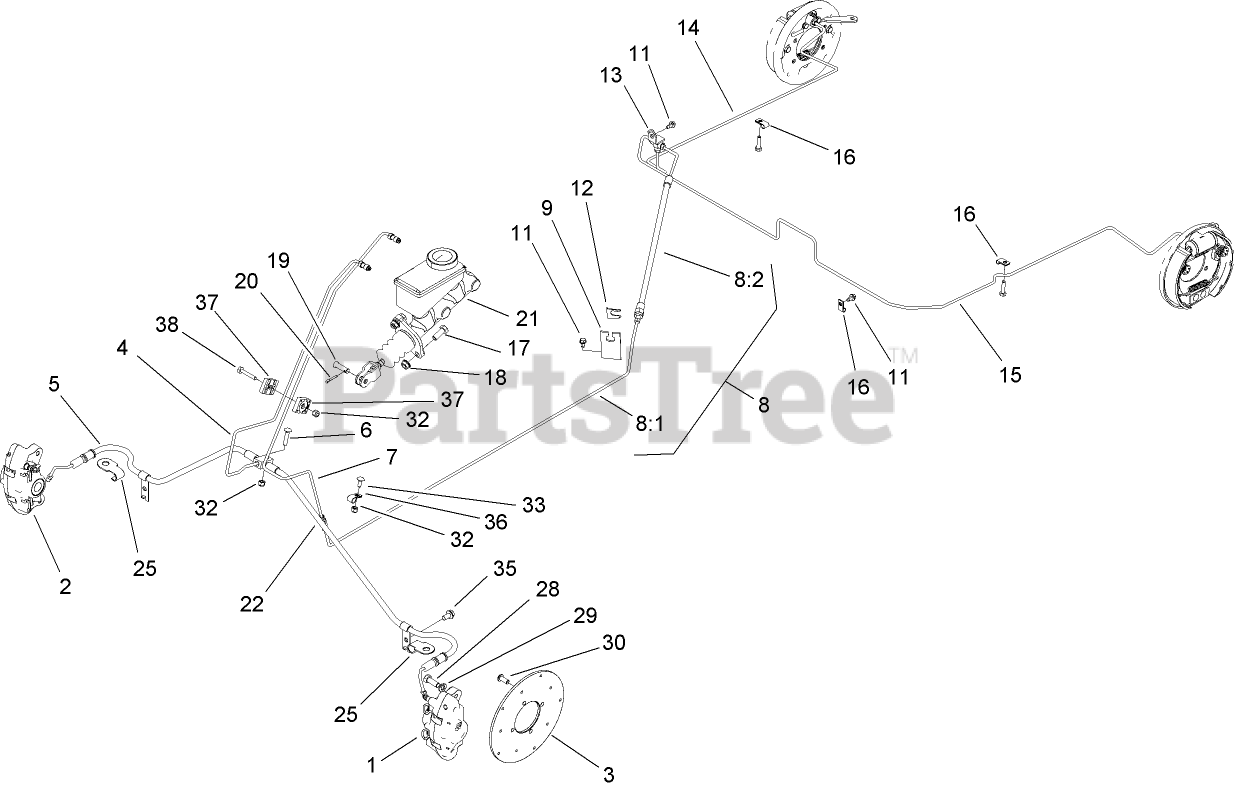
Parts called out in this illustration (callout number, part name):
1	CALIPER-LH
2	SEE PARTS BULLETIN #977
4	TUBE-BRAKE, FRONT
6	SCREW-CARR
7	TUBE-BRAKE, REAR
8	Loose Parts Package
8:1	TUBE-BRAKE, REAR
8:2	HOSE-BRAKE, REAR
9	BRACKET-HOSE, BRAKE
11	SCREW
14	TUBE-BRAKE, REAR (RH)
15	TUBE-BRAKE, REAR (LH)
16	CLIP-CLOSED, INSULATED
17	SCREW-HH
18	NUT-HHF, WHIZ
19	PIN-CLEVIS
20	PIN-COTTER
21	MASTER CYLINDER ASM
22	UNION
25	BRACKET-HOSE
28	SCREW-HH
29	WASHER-LOCK
30	SCREW-HSBH
32	NUT-LOCK, NI
33	SCREW-CARR
35	SCREW-HWHTF
36	CLAMP-R
37	CLAMP-TUBE
38	SCREW-HH
